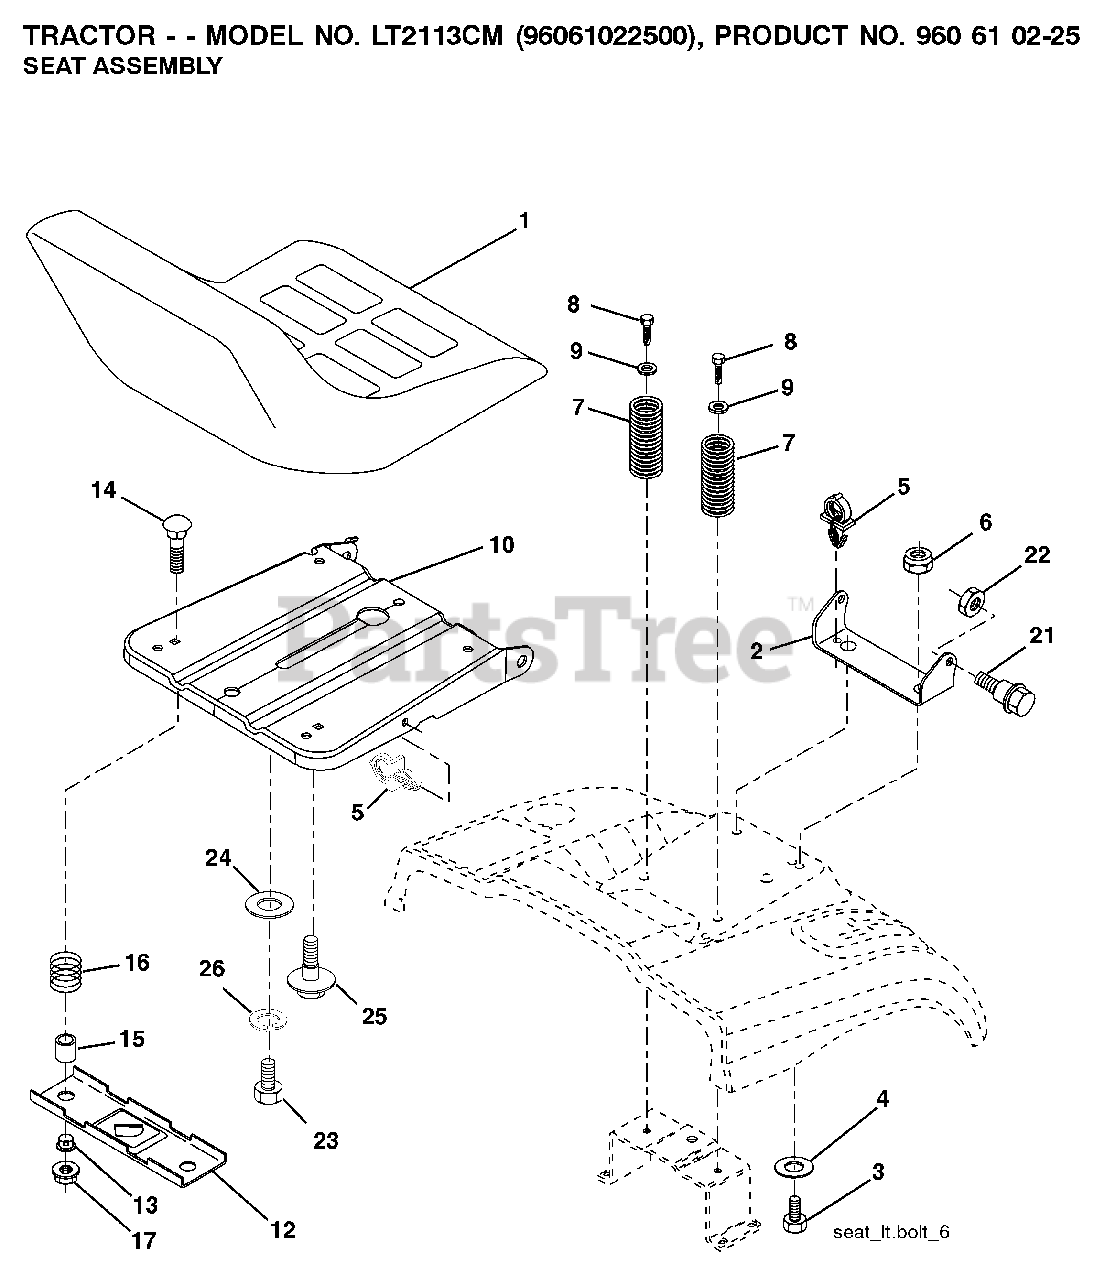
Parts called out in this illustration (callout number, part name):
1	SEAT.XG090.BLK.KB/BLT.NO-LOG
2	SEAT PIVOT BRKT
4	WASHER PM
5	PUSH CLIP
6	NUT
7	SPRING COMPRESSION
8	SCREW 3/8-16X1
9	WASHER
10	PAN.ASM.SEAT.1SLOT
12	BRKT.MNTNG.SWITCH.SEAT
14	BOLT.ROUND.HEAD.SQUARE.NECK
15	SPACER SPLIT 28X.96
17	NUT T
21	BOLT.SHOULDER.5/16-18
22	NUT.71038.31-18.HEX.NYLOCK
23	BOLT.HEX.BLACK
25	BOLT,SHOULD
26	LOCKWASHER
